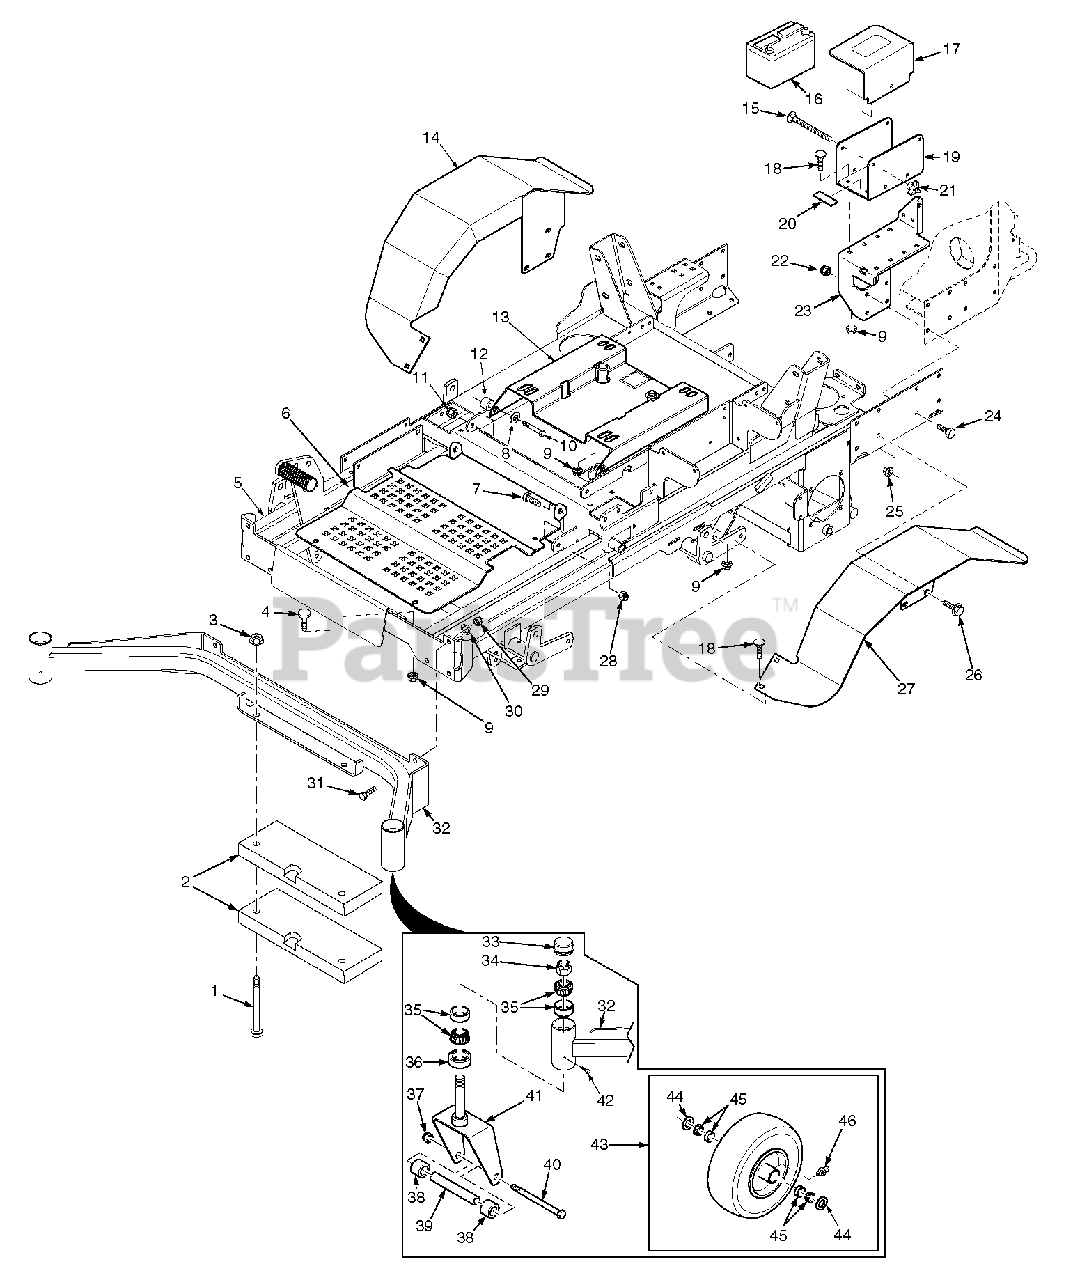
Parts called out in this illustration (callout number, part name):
1	Bolt, Hex Head 1/2-13 x 3.5"
2	Weight
3	Nut, Hex Elastic Stop 1/2-13
4	Bumper, Rubber 5/16-18 x 5/8"
5	Main Frame Assembly w/Decals
6	Foot Plate
7	Bolt, Hex Head 3/8-16 x 1"
8	Flatwasher, 3/8-.391 x .938 x .105
9	Nut, Hex Serrated Flange 5/16-18
10	Bolt, Hex Head 3/8-16 x 2.0"
11	Nut, Elastic Stop 3/8-16
12	Spacer Bushing
13	Seat Plate Weldment w/Decal
14	Fender Weldment, RH
15	Bolt, Carriage 1/4-20 x 6"
16	Battery (not avail. through Scag)
17	Cover, Battery
18	Bolt, Carriage 5/16-18 x 3/4"
19	Plate, Battery Box
20	Rubber Pad
21	Wing Nut, 1/4-20 x 3/4"
22	Nut, Elastic Stop 3/8-16
23	Battery Box Mount
24	Bolt, Hex Head 3/8-16 x 1"
25	Nut, Hex Serrated Flange 3/8-16
26	Screw, Hex Serrated Flange 3/8-16 x 1"
27	Fender Weldment, LH
28	Nut, Hex Elastic Stop 3/8-16
29	Nut, Elastic Stop 7/16-14
30	Lockwasher, 7/16"
31	Bolt, Hex Head 7/16-14 x 1-1/4"
32	Extention Weldment, Caster (Use with 61" Deck)
32	Extention Weldment, Caster (Use with 72" Deck)
33	Cap, Grease
34	Nut, Hex Elastic Stop 1.0"-14
35	Bearing W/Race
36	Seal, 2.00" OD. x 1.625" Bore
37	Nut, Hex Elastic Stop 1/2-13
38	Spacer, Caster Wheel
39	Sleeve, Caster Wheel (61V)
40	Bolt, Hex Head 1/2-13 x 9-1/2" (61V)
41	Yoke Weldment, Caster (61V )
42	Plug, 1/4-28 THD Form
43	Wheel Assembly,
45	Bearing w/ Race
46	Grease Fitting
